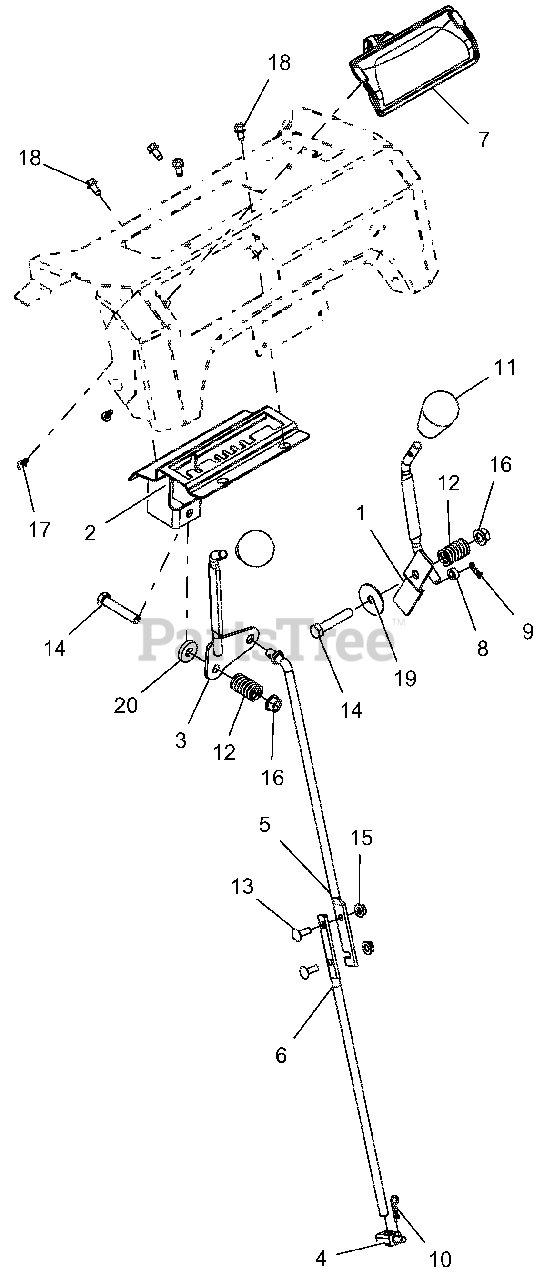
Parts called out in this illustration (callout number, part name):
1	WELDMENT, CONTROL LEVER (DEFL)
2	WELDMENT, DETENT PLATE-COMPACT
3	LEVER, CONTROL-SHIFT(WELDMENT)
4	PIVOT,SHIFT ROD .375-16(TRUNN)
5	ROD, SHIFT - UPPER
6	ROD, SHIFT - LOWER
7	HEADLIGHT ASY, HALO 20W 2SHOT
8	BSHG-SLV .265X.500X.219
9	PIN-HAIR INT .06X.18X.77
10	PIN-HAIR INT .08X.18X1.18 YWZC
11	KNOB,SOFT TEARDROP,PUSH-ON GRY
12	SG-COMP .125X.781X1.250
13	@BLT-RDHDSQNK .25-20X.75 G5YZ
14	@BLT-HEX .38-16X2.00 GR5 YWZC
15	@NUT-LK-CTR-FLG .25-20 YWZC
16	@NUT-LK-TOP-FLG .38-16 YWZC
17	SCR-TAP #10X.50 BOSS INDHXHD
18	SCR-TAP .25-20X.50 HWH TR YWZ
19	WSHR-FL-STL .380X1.50X.062 YWZ
20	WSHR-FL-STL .406X1.00X.188 YWZ
